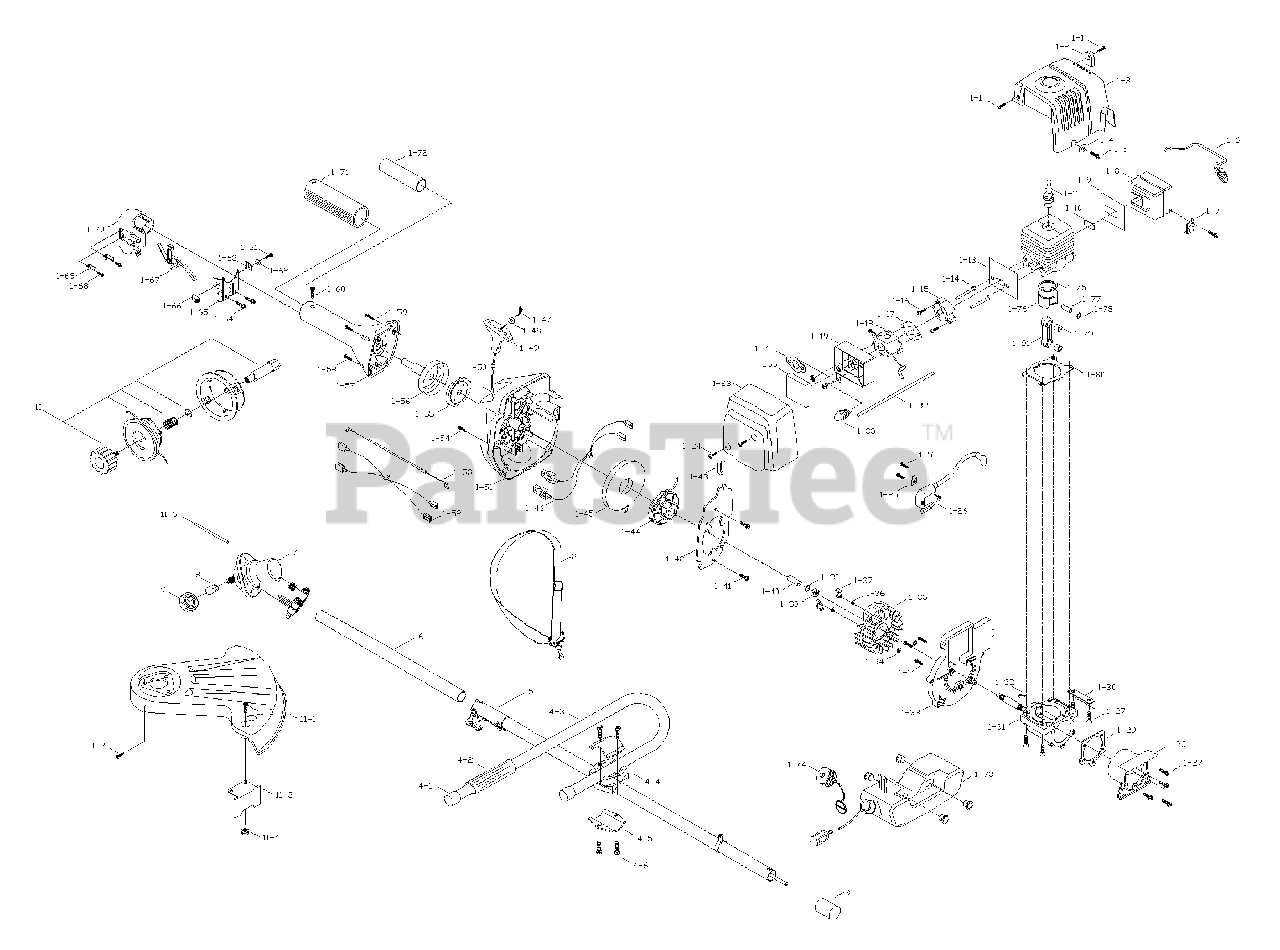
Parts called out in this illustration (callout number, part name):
1	ENG ASS'Y
1-1	SCREW
1-2	WASHER, PLASTIC
1-5	SCREW
1-6	SPRING, MUFFLER
1-7	SCREEN, SPARK ARRESTER
1-8	KIT, MUFFLER
1-9	GASKET, MUFFLER
1-10	GASKET
1-11	SPARK PLUG
1-12	KIT, CYLINDER/GASKET
1-13	GASKET, MUFFLER
1-14	SCREW
1-15	MANIFOLD, CARBURETOR
1-16	SCREW
1-17	GASKET, CARBURETOR
1-18	CARBURETOR ASS'Y
1-19	BOX, AIR
1-21	GASKET
1-22	FILTER, AIR
1-23	COVER, AIR CLEANER
1-25	TERMINAL TAB
1-26	IGNITION ASSEMBLY
1-27	SCREW
1-28	PLUG, C'CASE
1-29	GASKET
1-30	SHIELD, MUFFLER
1-31	C'CASE ASS'Y
1-32	KEY, FLYWHEEL
1-33	SHIELD MUFFLER
1-34	RING, RETAINER
1-35	FLYWHEEL
1-37	PAWL KIT, STARTER
1-41	SCREW
1-42	RETAINER, PULLEY
1-43	GROMMET
1-44	DRUM/ ROPE ASS'Y
1-45	PACKAGE, SPRING ASS'Y
1-46	WIRE ASS'Y
1-47	ROPE, STARTER
1-48	WASHER, NYLON
1-49	HANDLE, STARTER
1-50	GUIDE, ROPE
1-52	WIRE ASS'Y, SWITCH
1-53	THROTTLE CABLE ASS'Y
1-55	KIT ASS'Y, CLUTCH
1-56	DRUM ASS'Y, CLUTCH
1-57	HOUSING, CLUTCH
1-58	SCREW
1-59	SCREW
1-60	SCREW
1-61	SCREW
1-63	CONTACT, SWITCH
1-65	COVER ASS'Y, SWITCH
1-66	BUTTON, STOP SWITCH
1-67	TRIGGER, THROTTLE
1-69	TERMINAL TAB
1-70	TRIGGER HOUSING
1-72	SLEEVE, PROTECTING
1-73	TANK ASS'Y FUEL
1-74	CAP, FUEL TANK
1-75	RING, PISTON
1-76	KIT, PISTON
1-77	PIN, C,SHAFT PISTON
1-78	RING, RETAINING
1-80	GASKET, CYLINDER
1-81	ROD, CONNECTING
2	HARNESS
4	HANDLE ASS'Y
4-2	J HANDLE
4-3	PLUG
4-4	CENTERPIECE
4-5	CLAMP
4-6	SCREW
5	HOUSING ASS'Y, OUTER
6	HOUSING ASS'Y, FRONT
7	GEAR HOUSING ASS'Y
8	SPLINE SLEEVE
9	COLLAR
10	STRINGHEAD ASS'Y
11	GRASS SHIELD ASS'Y
11-2	SCREW
11-4	NUT
